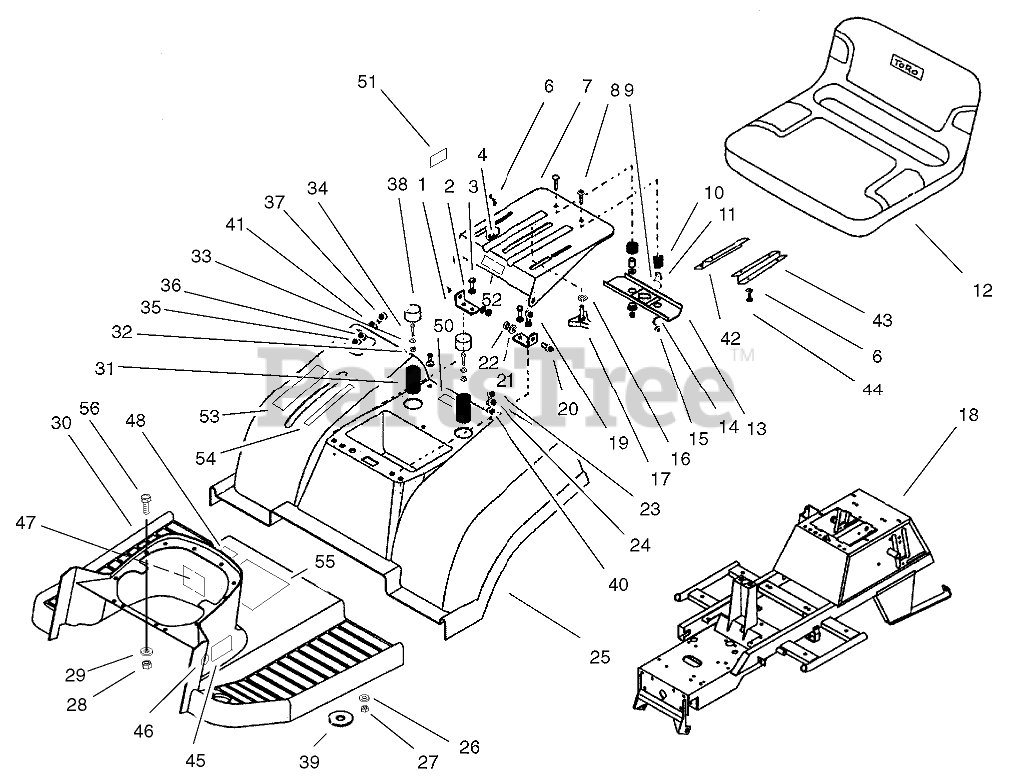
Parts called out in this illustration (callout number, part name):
1	BRACKET-SUPPORT, SEAT
2	WASHER-SPRING
3	SCREW-HH
4	BOLT-HEX
6	WASHER-SPRING
7	SUPPORT-SEAT
8	BOLT-CARRIAGE
9	WASHER-FLAT
10	SPRING-SEAT
11	SPACER-SPLIT
12	SEAT
13	BRACKET
14	BUSHING
15	NUT-LOCK
16	WASHER-SPRING
17	KNOB-ADJUSTMENT
18	FRAME-CHASSIS
19	SCREW-HH
20	SCREW-SUPPORT, SEAT
21	WASHER-PLAIN
22	NUT-LOCK, NI
23	SCREW-HSFH
24	WASHER-FINISH
25	FENDER
26	WASHER-FLAT
27	NUT-LOCK, NI
28	NUT-LOCK
29	WASHER-FLAT
30	FOOTREST ASM
31	SPRING-SEAT
32	NUT-LOCK, NI
33	WASHER-PLAIN
34	SCREW-HH
35	NUT-LOCK
36	WASHER-FLAT
37	BOLT-CARRIAGE
38	CAP-HUB
39	WASHER-RUBBER
40	WASHER-RUBBER
41	WASHER-RUBBER
42	BRACKET-RIGHT SEAT
43	BRACKET-LEFT SEAT
44	Screw
45	DECAL - TOWER 170DH
46	DECAL-BRAKE, PARKING
47	DECAL-STARTING
48	DECAL-OPERATION, HYDRO
50	DECAL-BAG TO FRAME
51	DECAL-SWITCH
52	DECAL-DANGER
53	DECAL-HOC, RH
54	DECAL-HOC, LH
55	DECAL-INSTRUCTION
56	SCREW-HH
